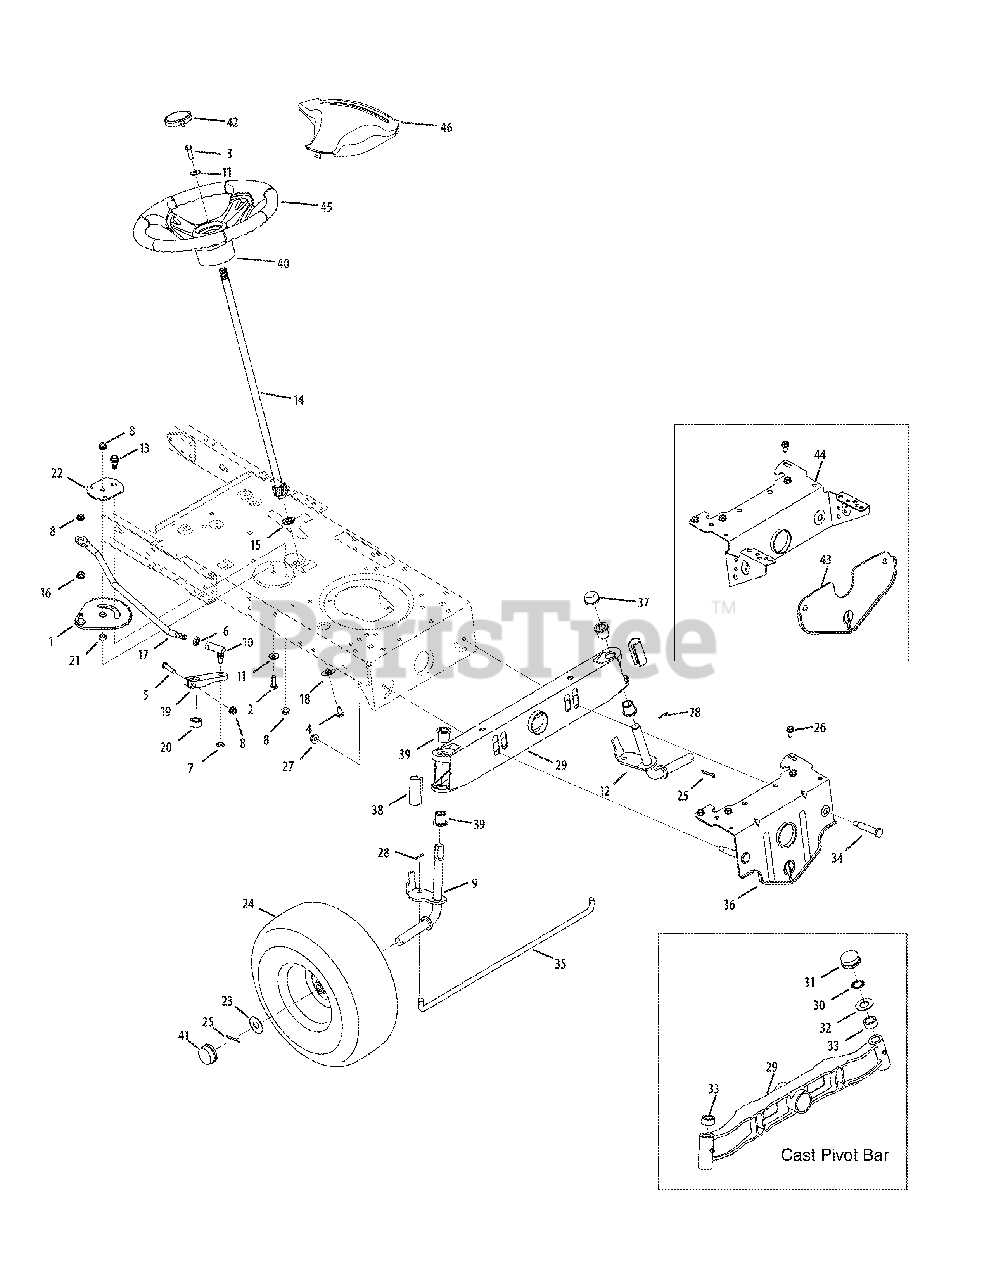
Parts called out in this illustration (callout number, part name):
1	Steering Gear Assembly
2	Hex Scr 5/16 x 1,00 Gr. 5
3	Hex Screw 5/16-18 x 1.00 Special
4	Machine Screw 5/16-18 x .75
5	Hex Screw 5/16-18 x 1.75" Lg.
6	Hex Jam Nut 7/16-20
7	Hex Cent-L Nut 3/8-24 Gr. B
8	Flange Locknut 5/16-18 Gr. F, Nylon
9	Axle Assembly, RH
10	Ball Joint, 7/16 - 20
11	Cupped Washer .345 ID x .88 OD x .060
12	Axle Assembly, LH
13	Shoulder Screw .435 x .3485, 5/16-18
14	Steering Shaft, 5/8 Spline x 21.86
15	Hex Flange Bearing 5/8
16	Plastic Bushing .375 ID x .5
17	Steering Drag Link
18	Cap, 1.25 x .16
19	Steering Block
20	Spacer .710 ID x .125 OD x .56
21	Spacer .322 ID x .625 OD x .21
22	Stabilizer Plate, Gear Segment
23	Flat Washer .781 ID x 1.59 OD Special
24	Wheel Assembly Complete 15 x 6 x 6.5
25	Cotter Pin 5/32 x 1.25
26	S-Tapp Scr 5/16-18 x .75
27	Flange Lock-Nut 3/8-16 Gr. F, Nylon
28	Cotter Pin 1/8" Dia x .75
29	Pivot Bar
29	Pivot Bar (cast)
30	Push Nut 3/4"
31	Axle End Cap
32	Flat Washer .78 x 1.59 Special
33	Spacer .71 x .125 x .56
34	Shoulder Screw .500 x 2.380, 3/8-16
35	Tie Rod
36	Pivot Bar Bracket
37	Push Cap, .750
38	Axle End Cap, Standard
39	Flange Bearing .760 ID x .937 OD
40	Steering Wheel, Standard Grip
41	Plastic Hub Cap
42	Steering Wheel Cap (sprig logo)
43	Front Deck Hanger Bracket
44	Pivot Bracket
45	Steering Wheel
46	Steering Wheel Cover - MT
